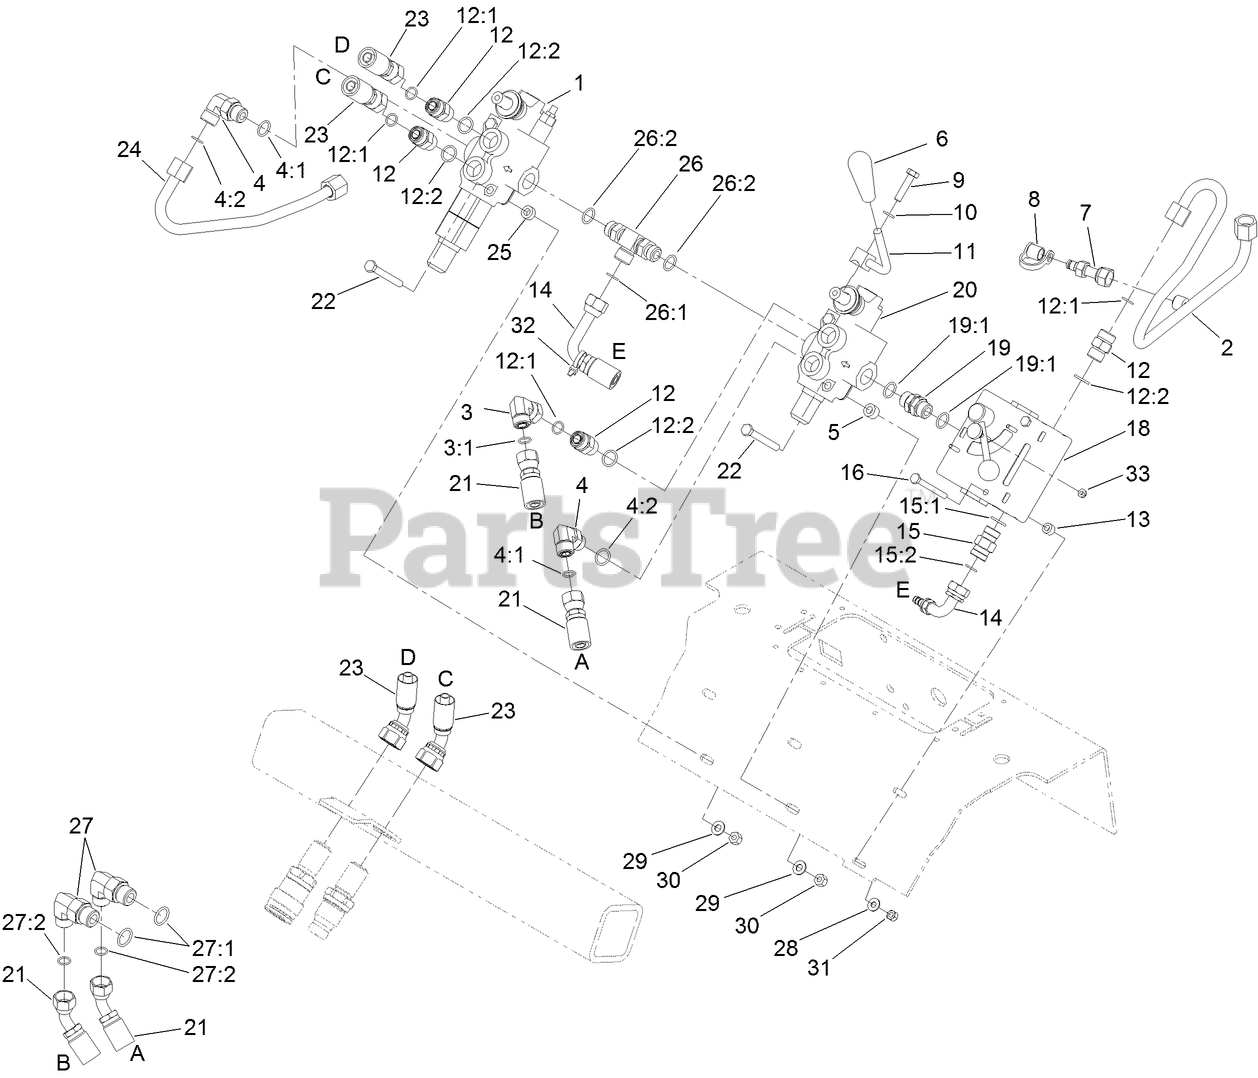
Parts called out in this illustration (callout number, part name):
1	VALVE-HYD, AUXILIARY
2	TUBE-HYD
3	FITTING-HYD
3:1	O-RING
4	FITTING-ELBOW-90 DEG
4:1	O-RING
4:2	O-RING
5	SPACER
6	KNOB-TAPERED
7	NIPPLE-TEST
8	CAP-DUST
9	SCREW-HH
10	WASHER-LOCK
11	LEVER-CONTROL
12	FITTING-STRAIGHT
12:1	O-RING
12:2	O-RING
13	SPACER
14	HOSE-HYD
15	VALVE-CHECK, HYD
15:1	O-RING
15:2	O-RING
16	SCREW-HH
18	HYD VALVE KIT
19	FITTING-THREAD, STRAIGHT
19:1	O-RING
20	VALVE-SELECTOR, HYD
21	HOSE-PUMP, HYD
22	SCREW-HH
23	HOSE-HYD
24	TUBE-HYD
25	SPACER
26	ADAPTER-TEE, ADJUSTABLE
26:1	O-RING
26:2	O-RING
27	FITTING-ELBOW 90
27:1	O-RING
27:2	O-RING
28	WASHER-FLAT
29	WASHER-PLAIN
30	NUT-LOCK, NI
31	NUT-LOCK, NI
32	TIE-CABLE
33	NUT-LOCK, NI
